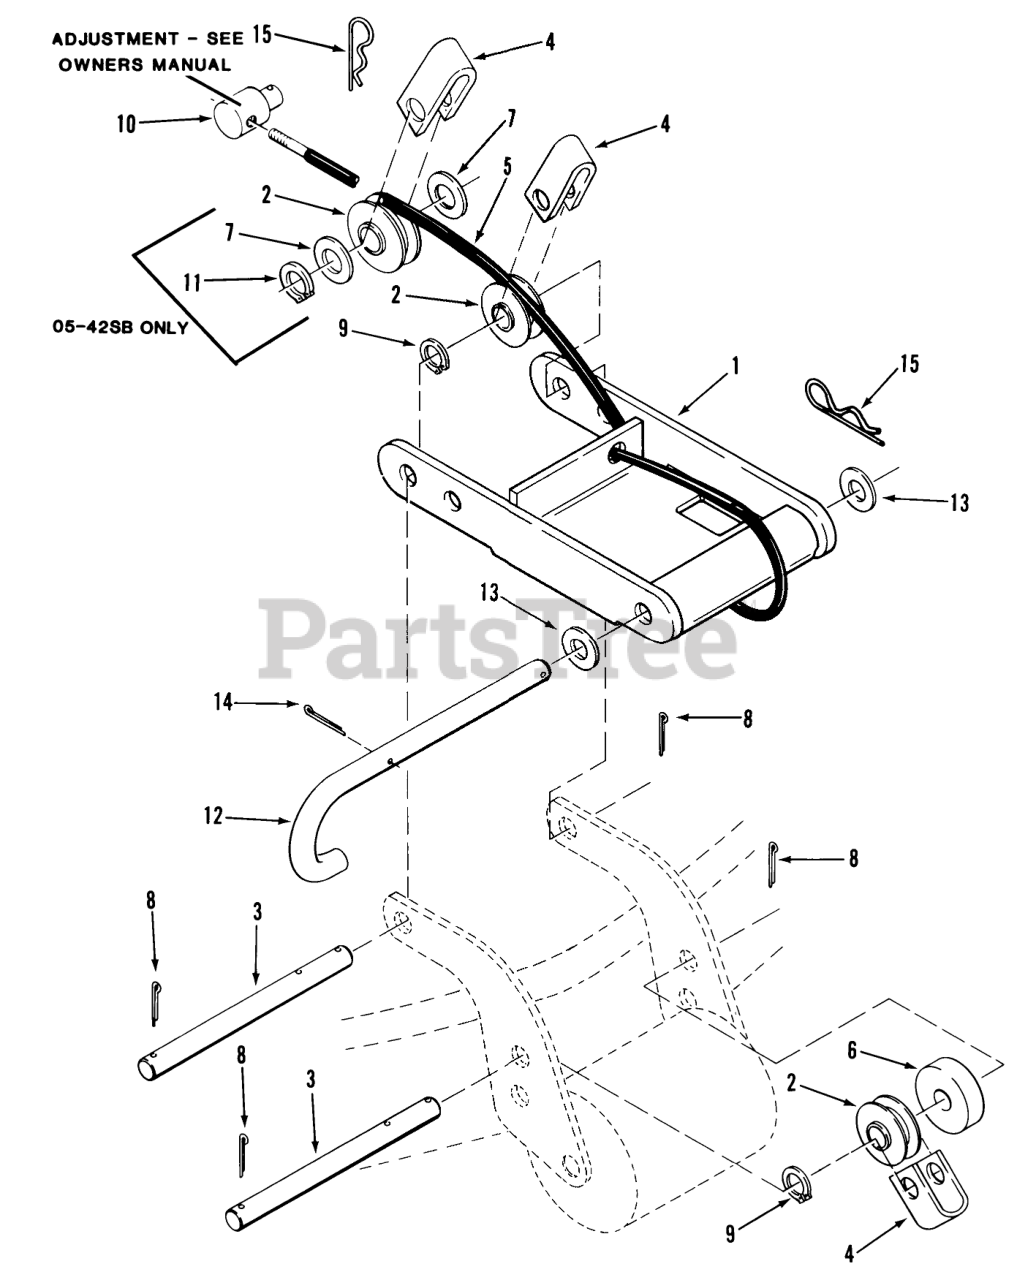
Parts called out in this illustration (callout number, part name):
1	Front Mount
2	ROLLER-CABLE
3	Rod
4	STRAP-CABLE
5	ASSY-CABLE 36IN&42IN
5	ASSY-CABLE
6	SPACER
7	Washer
8	Pop Rivet
9	GRIP RING
10	TRUNNION-CLUTCH ROD
12	"J" Pin
13	Washer
15	Hairpin Cotter
